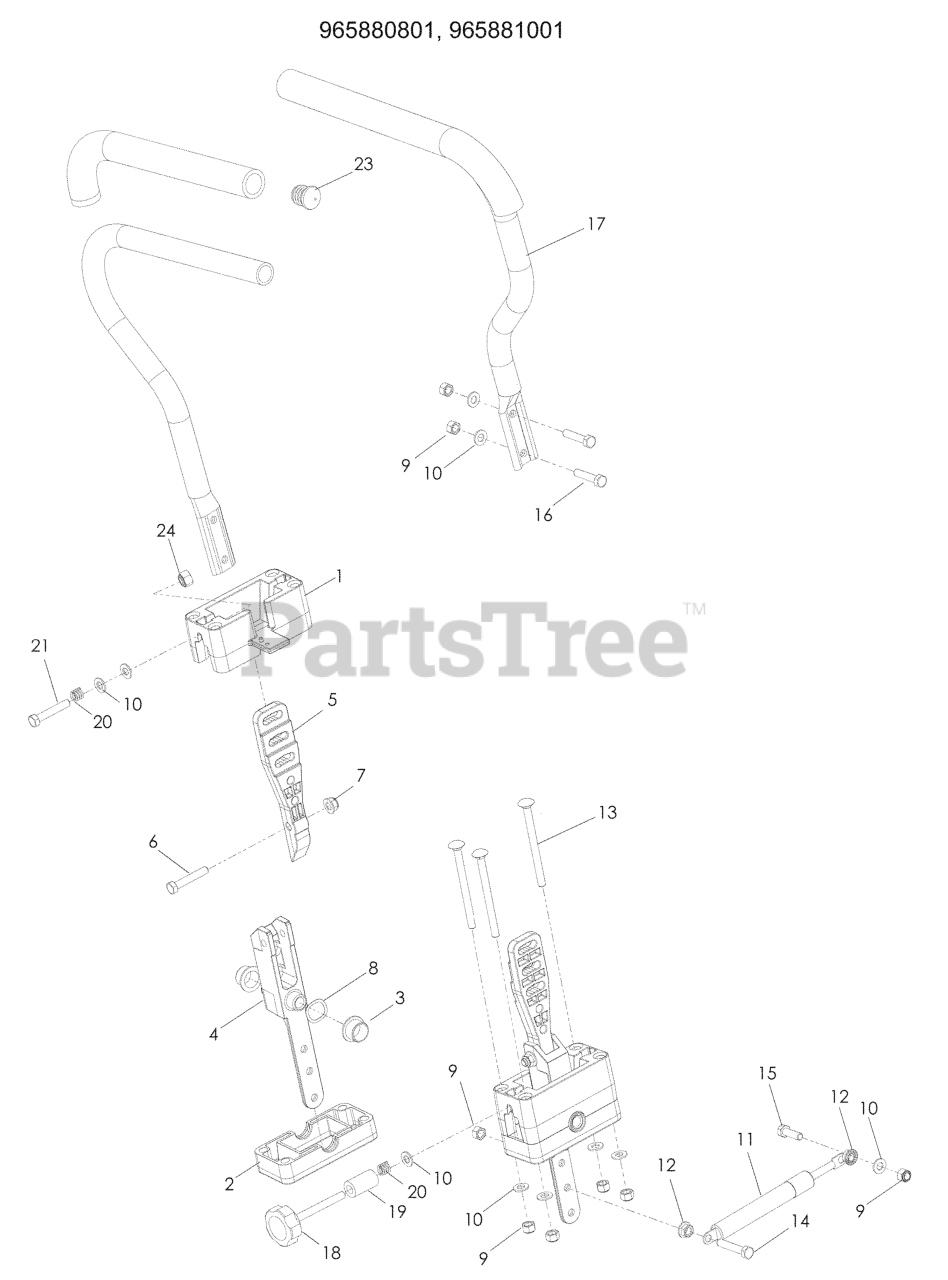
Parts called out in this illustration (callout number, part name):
1	BLOCK, UPPER
2	BLOCK, LOWER
3	BEARING, FLANGE
4	PIVOT.SECTION.DRIVE.CONTROL
5	MOUNT, DR CNTRL HANDLE
6	HCS 5/16C X 1 3/4
7	5/16-18 NYLOC FLANGE NUT
8	WASHER, .825 X 1.087, WAVE
9	NUT 5/16 NYLOC
10	FLAT WASHER 5/16 SAE
12	NUT 5/16C WHIZ
13	RHSNB 5/16-18 X 4 GR 5 ZD
14	HCS 5/16-18X1-3/4 TPBLT
15	HCS 5/16C X 1
16	CAPSCREW 5/16 X 1/1/2 HEX HEAD
17	LEVER.DRIVE.W/GRIP
19	DECK LIFT SPACER
21	HCS 5/16-18 X 2 TPBLT GR 5 ZD
22	GRIP, FOAM (GROUND) 15
23	END PLUG 15/16 (BLACK)
24	NUT 5/16C HEX
